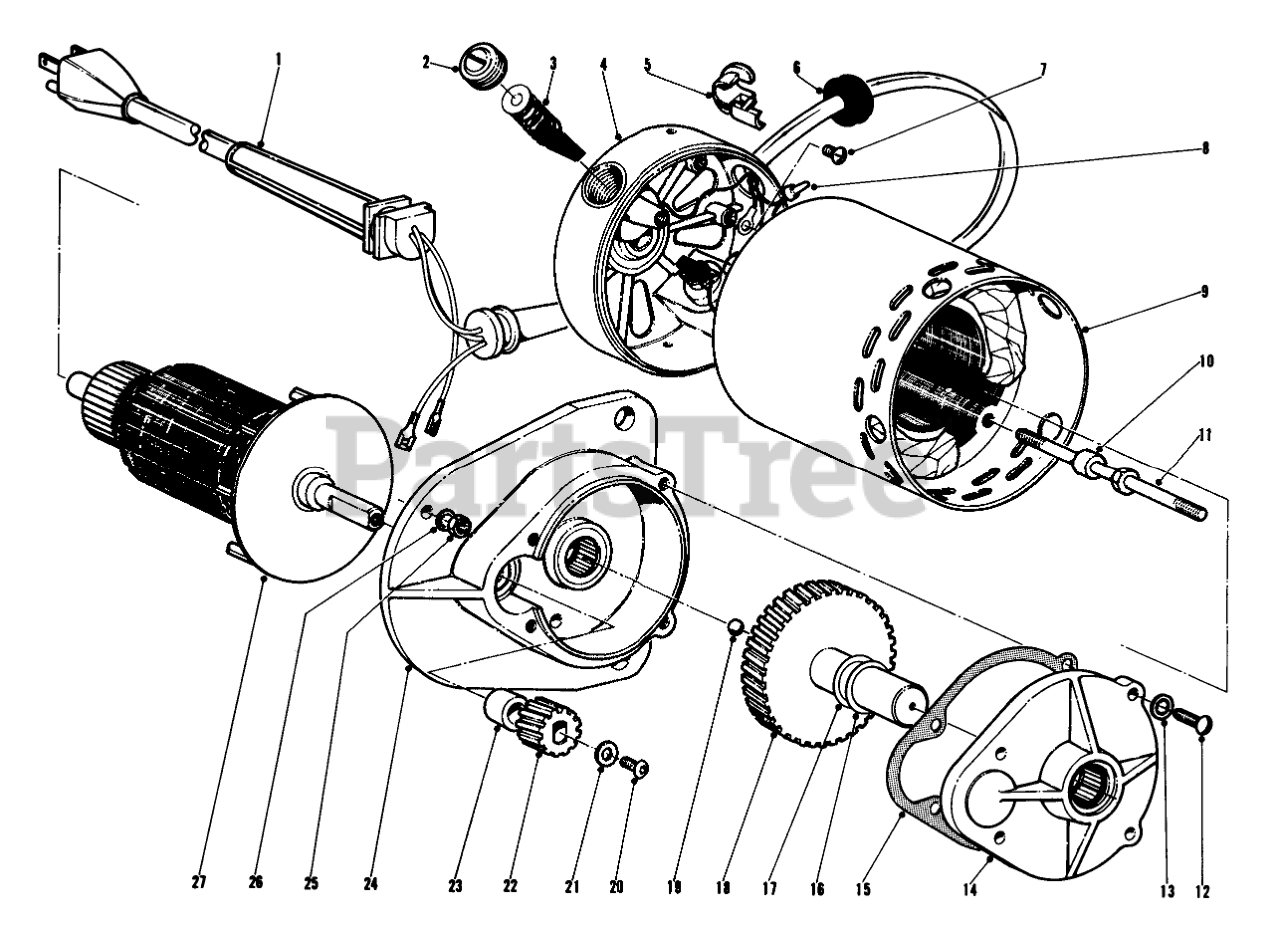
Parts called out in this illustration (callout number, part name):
2	Cap, Brush
3	Brush Assembly
4	Brush End Housing Assy.
5	Strain Relief
6	Grommet
7	Screw
8	Terminal
9	Frame & Field Assembly
10	Spacer
11	Stud
12	SCREW
13	WASHER-LOCK/INT
14	Gear Cover Housing
15	Gasket
16	Washer
17	Washer
18	Gear & Output Shaft Assy.
19	Ball
20	Screw
21	Washer
22	Pinion
23	Spacer
24	Gear Housing Assembly
26	WASHER-LOCK, INT
27	Armature Assy.
